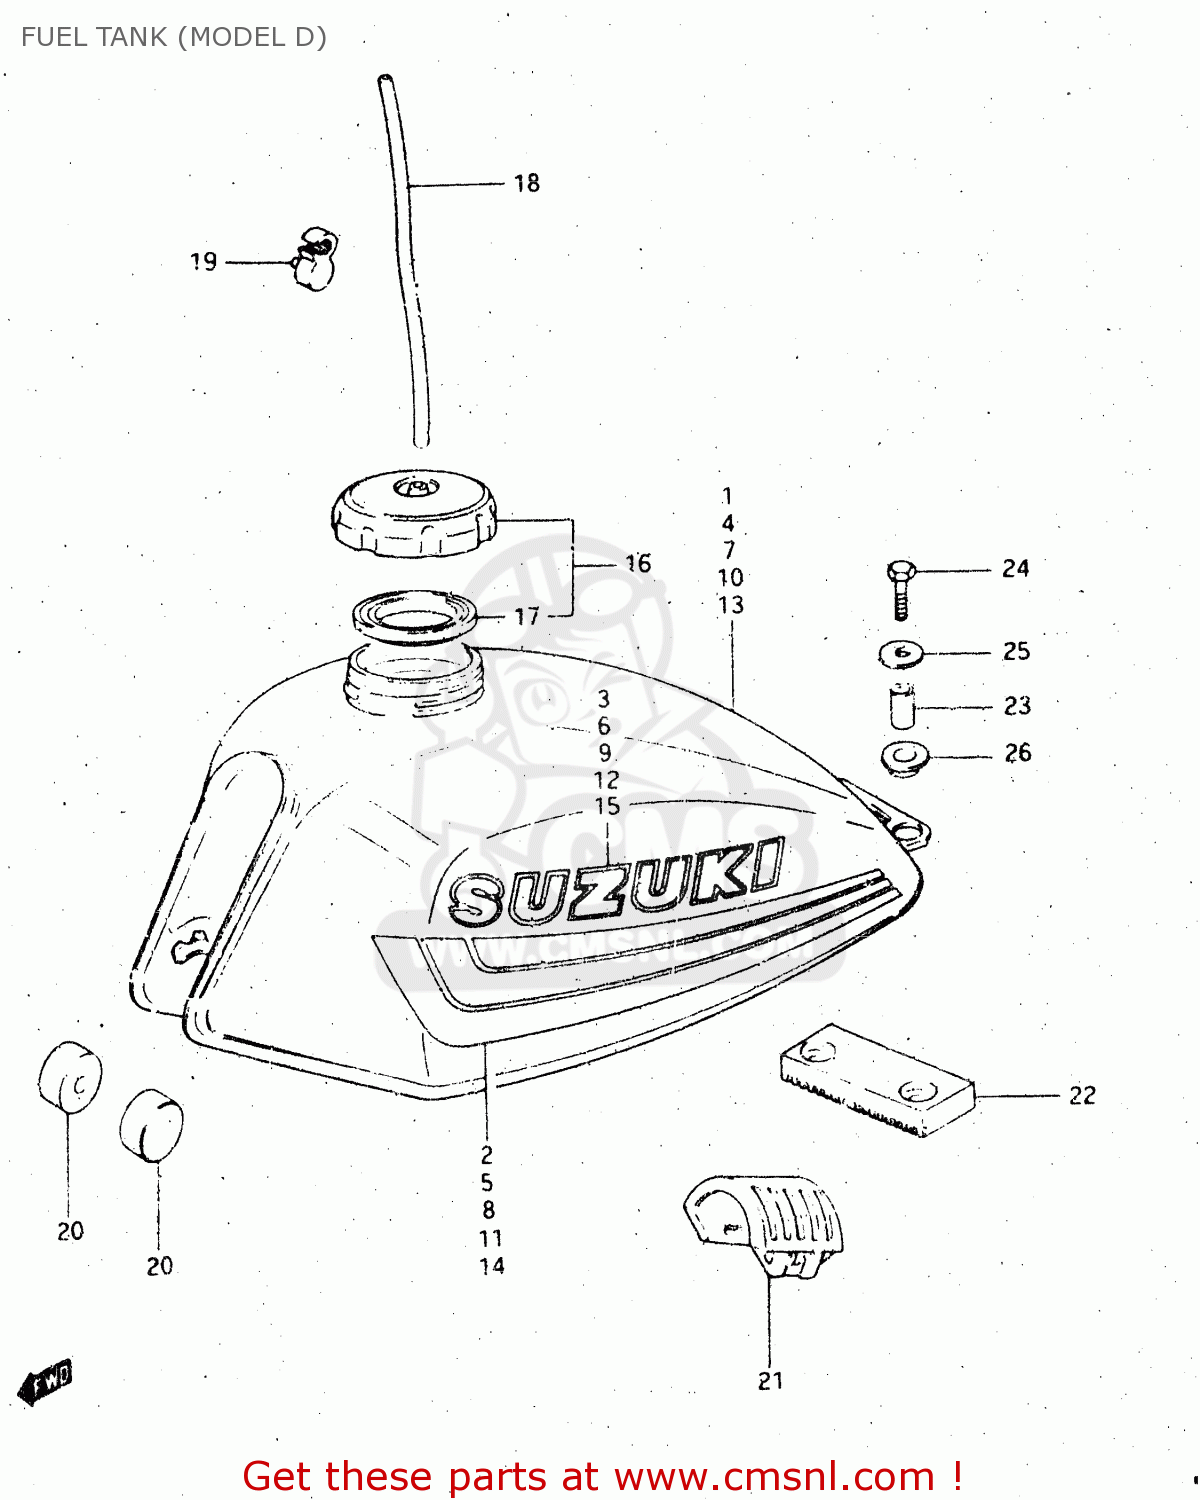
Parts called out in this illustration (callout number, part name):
1	TANK, FUEL (BLACK)
2	TAPE SET, FUEL TANK
3	EMBLEM,FUEL TANK(WHITE)
4	TANK ASSEMBLY,FUEL
5	TAPE SET,FUEL TANK
6	EMBLEM
7	TANK, FUEL (BLUE)
8	TAPE SET
9	EMBLEM,FUEL TANK(WHITE)
10	TANK, FUEL (RED)
11	TAPE SET
12	EMBLEM,FUEL TANK(WHITE)
13	TANK, FUEL (YELLOW)
14	TAPE SET,FUEL TANK
15	EMBLEM
16	CAP,FUEL TANK
17	GASKET,FUEL TANK CAP (NAS)
18	HOSE
19	CLAMP,FUEL TANK BREATHER HOSE
20	CUSHION
21	CUSHION,FUEL TANK UPR FR
22	CUSHION,FUEL TANK,REAR
23	SPACER (6.5X10.5X29)
24	BOLT 6X40
25	WASHER (6.5X24X1.6)
26	CUSHION
